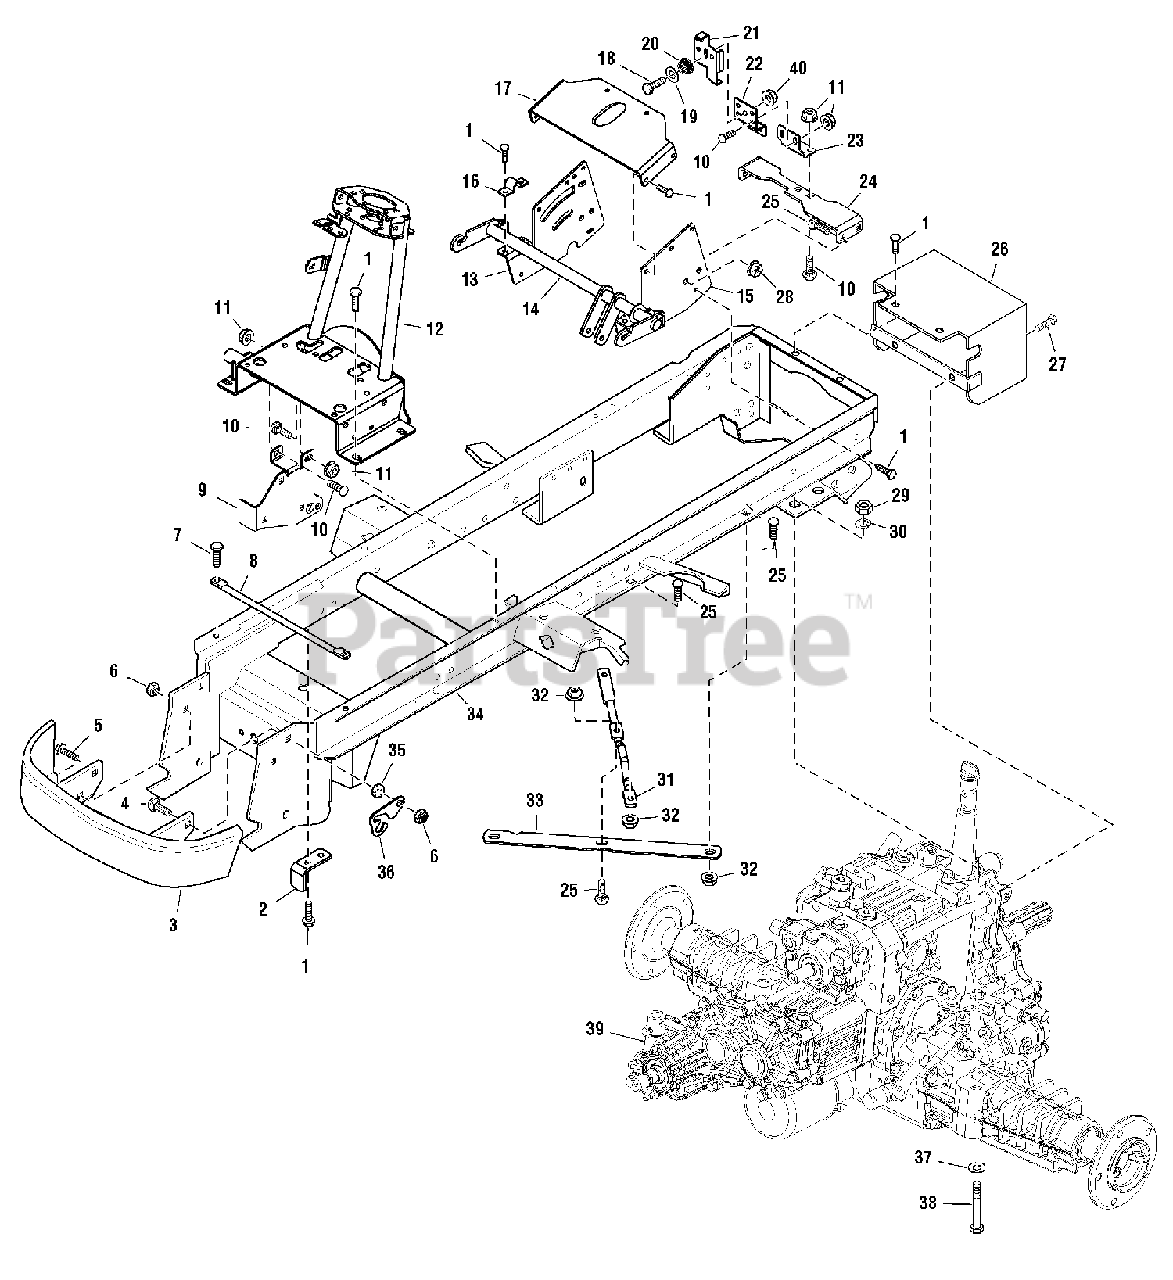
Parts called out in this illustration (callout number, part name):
1	CAPSCREW, Hex, Washer Head, Taptite, 5/16-18 x 3/4, Black
2	BRACKET, Upstop
3	BUMPER & BRACKETS ASSEMBLY
4	CARRIAGE BOLT-RD, 1/2-13 x 2, Black
5	CAPSCREW, Hex Head, 1/2-13 x 1-1/2, Black
6	NUT, Hex, Lock ESNA, 1/2-13
9	SUPPORT, Control Valve
10	CARRIAGE BOLT, 5/16-18 x 3/4, Black
11	NUT, Hex, KEPS 5/16-18, Black
12	TOWER ASSEMBLY
13	SUPPORT, Seat Support, RH
14	SHAFT ASSEMBLY
15	SUPPORT, Seat Support, LH
16	STRAP
17	SUPPORT, Seat Deck
18	CAPSCREW, Hex Head, 5/16-18 x 1, Black
19	WASHER, 5/16, Black
20	SPRING, Compresion, Conocal
21	BRACKET-FREE WHEEL 10GA
22	SUPPORT, Free Wheel Latch
23	SUPPORT, Dump Valve
24	BRACKET, Torque Strap
25	CARRIAGE BOLT, 3/8-16 x 1 Black
26	SHIELD & BRACKET ASSEMBLY
27	CAPSCREW, Hex Head, M12-1.75 x 25MM, (540 PTO Models Only)
28	NUT, Hex, Flange ESNA, 3/8-16, Black
29	NUT, Hex Flange Center Lock, M12-1.25, Black
30	LOCKWASHER, 1/2, Black
32	NUT, Hex, KEPS 3/8-16, Black
33	BRACE, Cross
34	FRAME ASSEMBLY
35	NUT, Hex, Jam, 1/2-13, Black
37	WASHER, 1/2
38	CAPSCREW, Hex Head, M12-1.25 x100MM, Black
39	TRANSMISSION ASSEMBLY, 4WD, K92C, W/540
39	TRANSMISSION ASSEMBLY, 2WD, K92A
39	TRANSMISSION ASSEMBLY, 4WD, K92B
40	NUT, Hex, Flange ESNA, 5/16-18, Black
41	COVER, PTO Shaft
